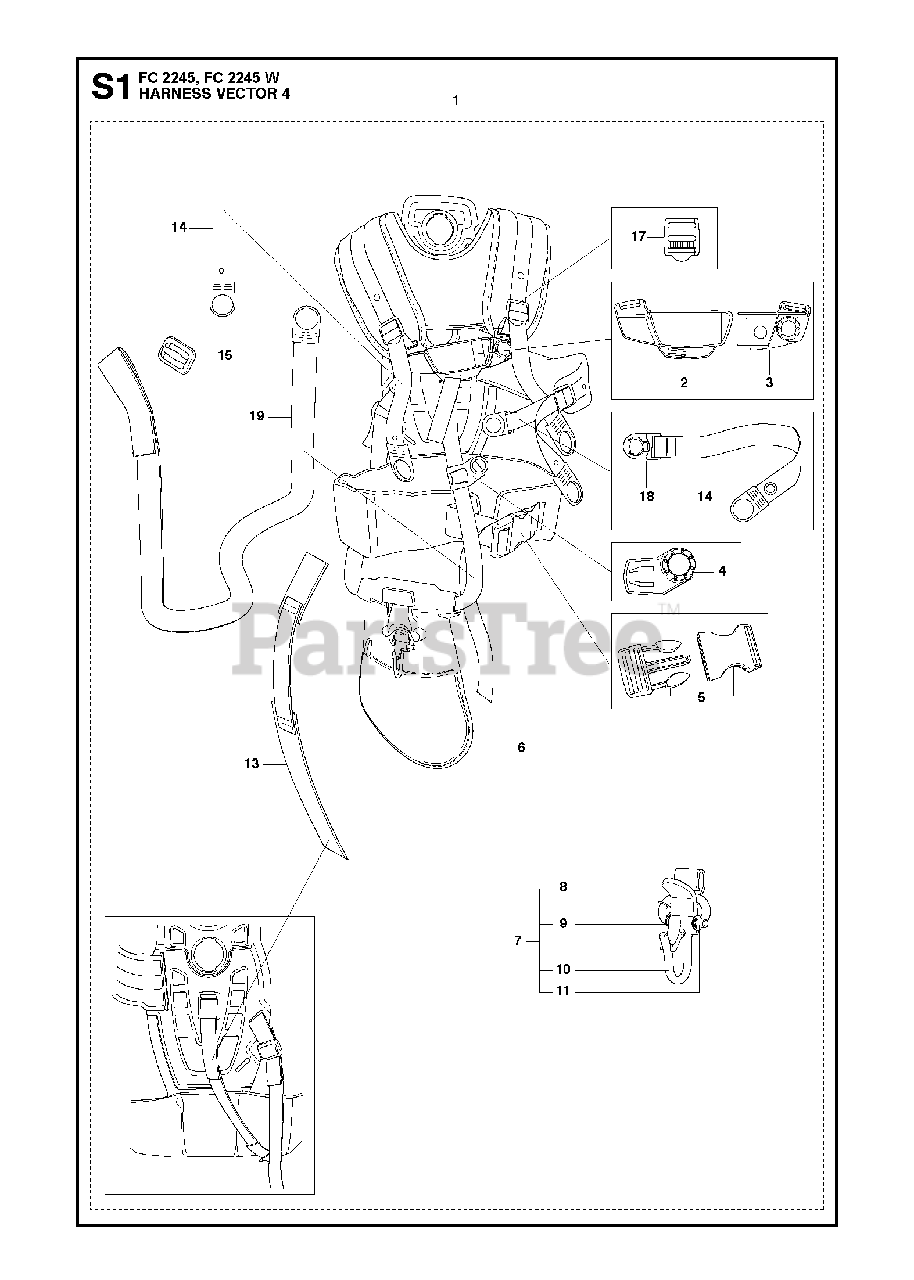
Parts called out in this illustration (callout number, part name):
5	BUCKLE
7	WELT HOOK
8	CATCH *
9	SPRING
10	HOOK
11	E-RING 5
15	CLIP
17	BUCKLE
18	SNAP LOCKING
